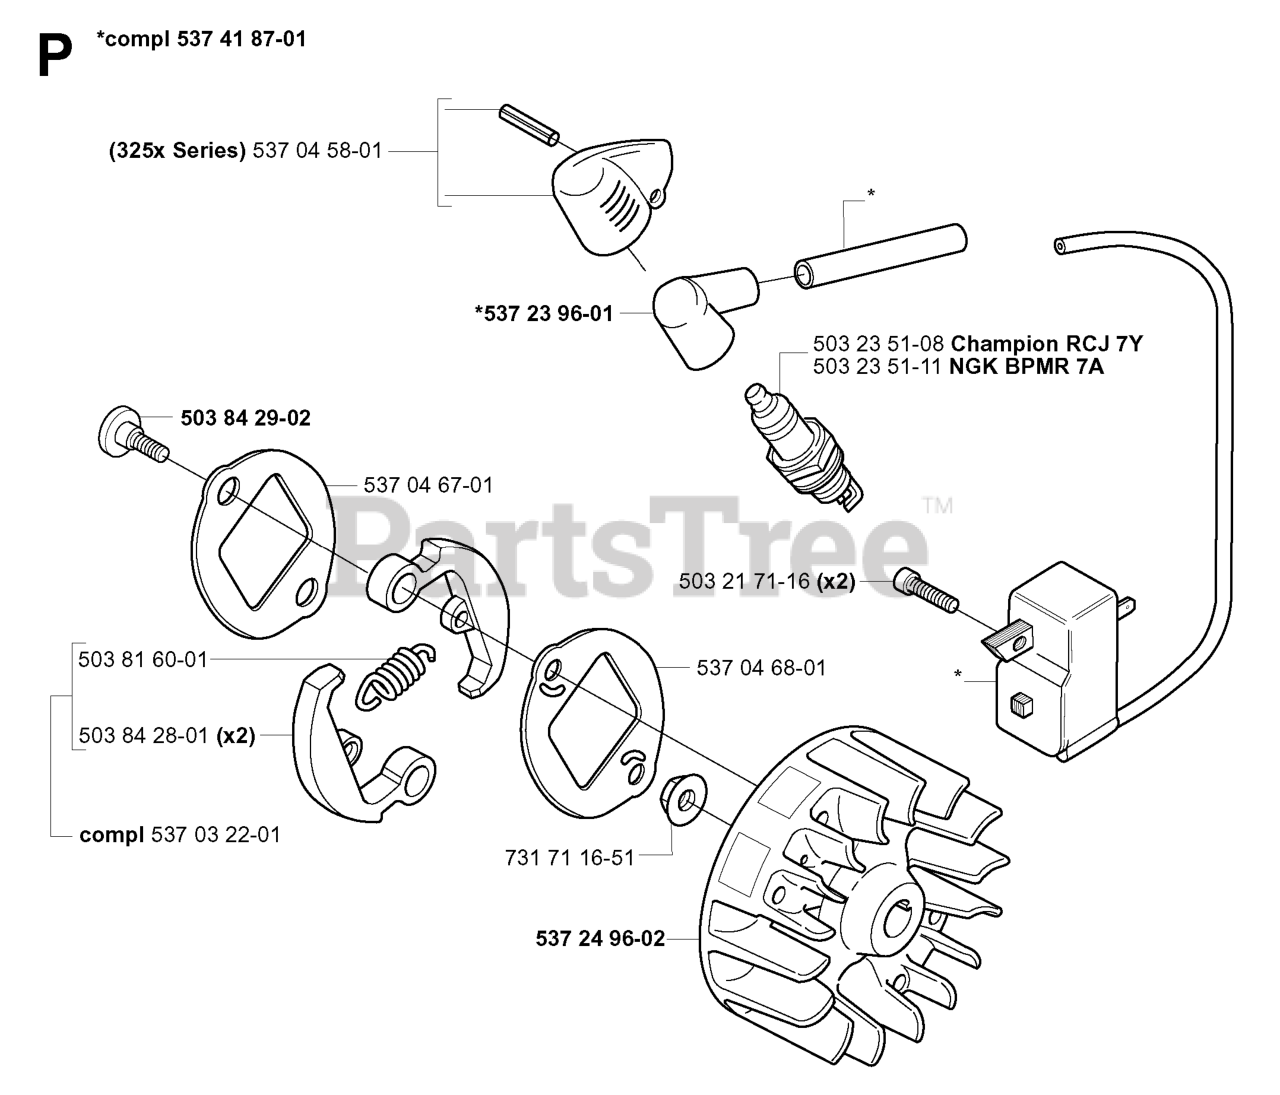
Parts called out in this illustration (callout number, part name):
1	V-BELT.IMPELLER
2	BELT.V.TRACTION.35.26
3	ARM.IDLER BRAKE.CLEAR.ZINC
4	PULLEY.W/SPACER.2.75
5	BRACKET.IDLER.PIVOT.ZINC
6	NUT.FLANGE.HEX.5/16X18.BLACK
7	HEX BOLT
8	BOLT.SHOULDER.1/2X12
9	NUT.LOCK.5/16-18
10	BOLT.5/16HEX.WHS.HD
11	ARM.ASM.TRACTION.IDLER.
12	BOLT.BLADE
13	STEEL WASHER
14	WASHER.400X1.25X5.
15	PULLEY IMPELLER.ASM.2.60_.75 B
16	PULLEY TRACTION.ASM.2.60_.75 B
18	WASHER.LOCK.HVY.HLCL.SPR.5/16
19	GUIDE.BELT.CHAIN.LS.SNOW
20	WASHER.20X8.5
21	BUSHING.BRAKE.ARM
22	CAPSCREW.HEXHD.5/16X1.25.
23	SCREW.3/8-16 X .750 (2 2)
